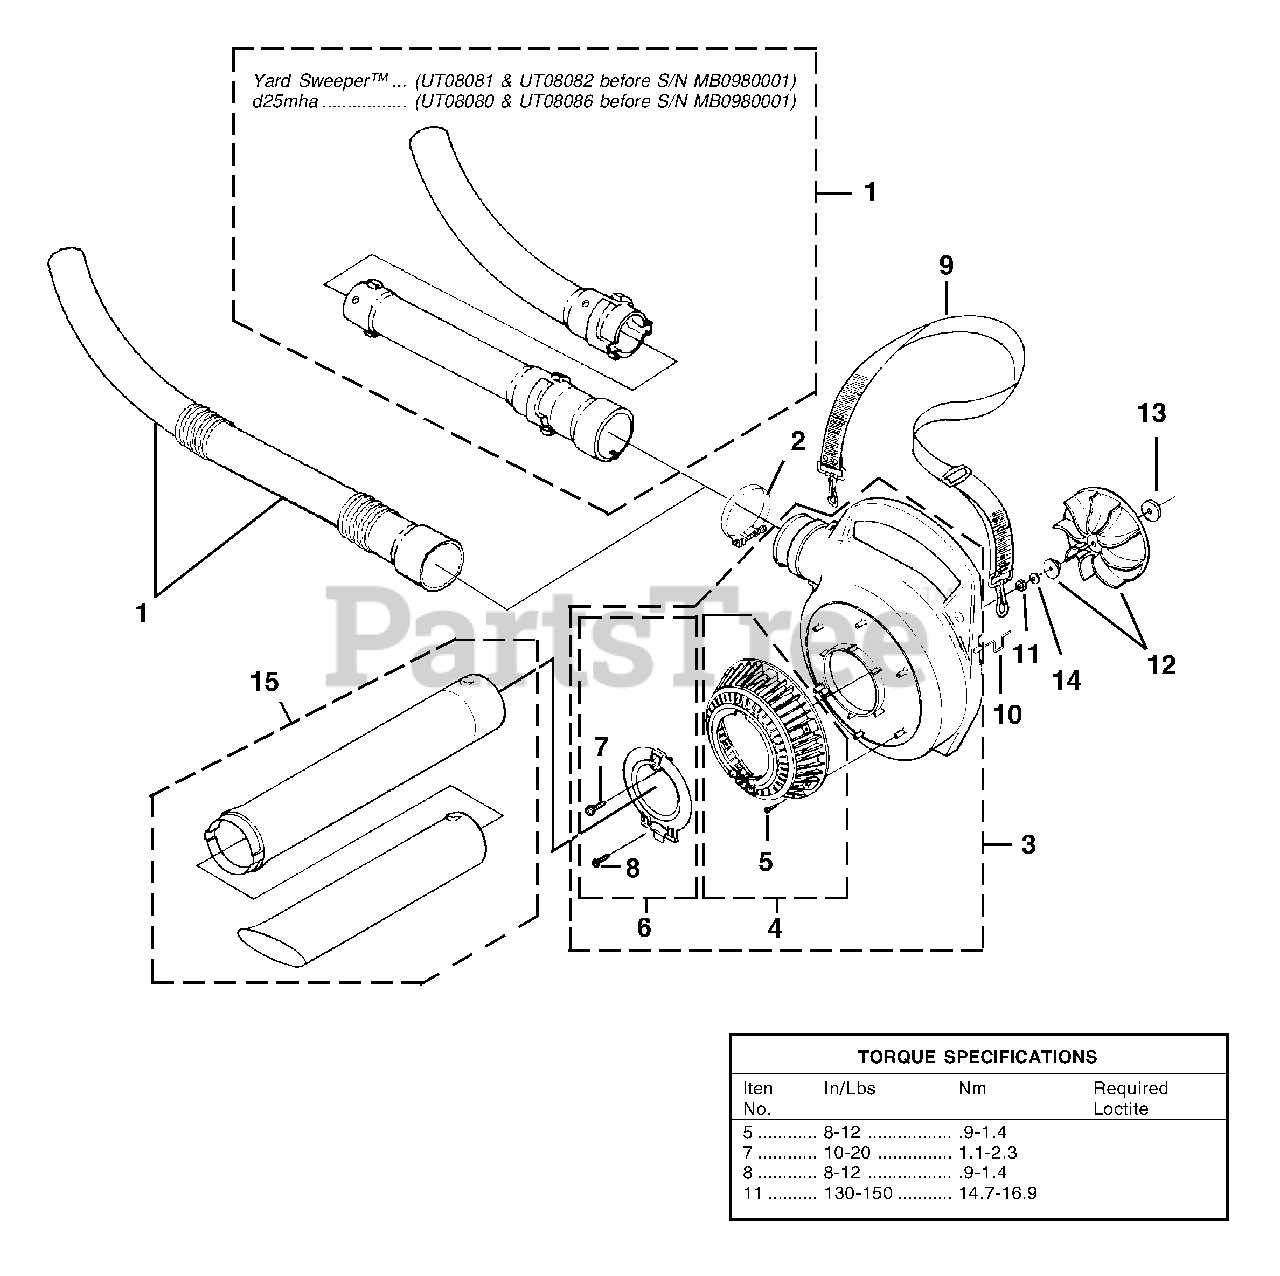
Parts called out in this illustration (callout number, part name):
1	BLOWER TUBE KIT
2	CLAMP w/Fasteners
3	VOLUTE HOUSING KIT
4	BLOWER VAC GRILLE KIT
5	SCREW-Thread Form. (#6 X 3/8")
6	ACCESS DOOR KIT
7	SCREW-Thread Rolling (#10 X 5/8")
8	SCREW-Thread Form. (#8 X 1/2")
9	SHOULDER STRAP
10	WIRE LOOP
11	NUT-Hex (3/8-24)
12	BLOWER FAN KIT
13	WASHER-Flat
14	WASHER-Bellville (3/8")
15	VACCUM TUBE KIT
